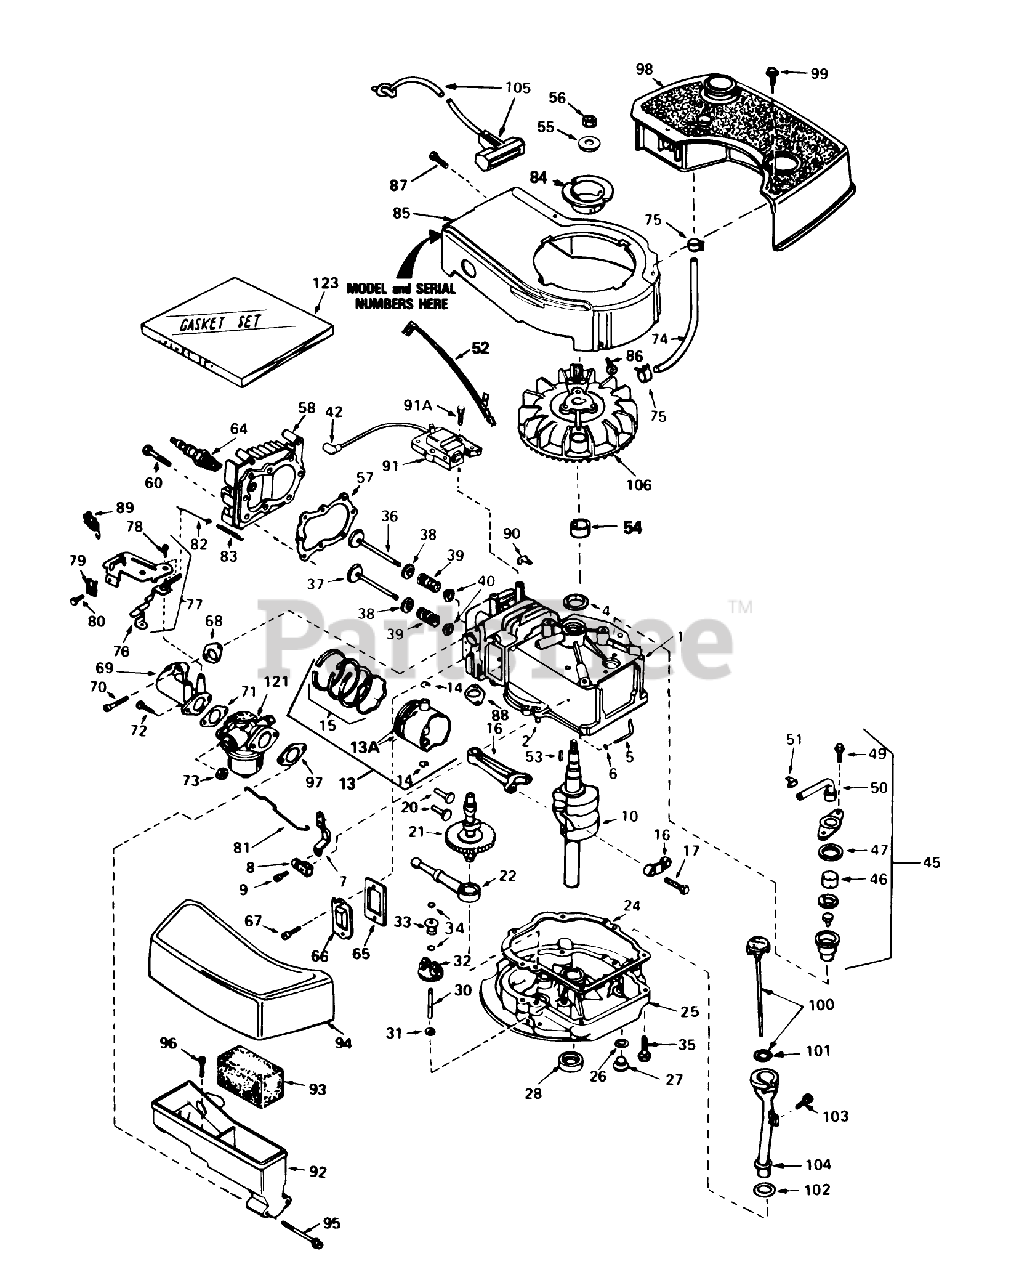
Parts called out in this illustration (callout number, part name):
1	Cyiinder Assy. (Incl. Ref. #2, 4 105)
2	Pin-Dowel
4	Seal-Oil
5	Rod, Governor (Incl. No. 36)
6	Washer-Flat
7	Governor Lever
8	Clamp-Lever, Governor
9	Screw
10	Crankshaft
13	Piston, Pin Ring Assy. (Std.) (Incl. Ref. #13A, 14 15)
13	Piston, Pin Ring Assy. (.010 oversize) (Incl. Ref. #13A, 14 15)
13	Piston, Pin Ring Assy. (.020 oversize) (Incl. Ref. #13A, 14 15)
13A	Piston Pin Assy. (Incl . Ref. . #14) (Std.)
13A	Piston Pin Assy. (Incl. Ref. #14) (.010 Oversize)
13A	Piston Pin Assy. (.020 oversize) (Incl. Ref. #14)
14	Ring-Retaining, Piston Pin
15	Ring Set (Std.)
15	Ring Set (.020" OS)
15	Ring Set (.010" OS)
16	Rod Assy., Connecting (Incl. Ref. #17)
17	OA Bolt-Connecting Rod
20	Lifter-Valve
21	Camshaft(Mech.Comp. Release)
22	Oil Pump ASM
24	Gasket, Mounting
25	Flange Assy., Mounting (Incl. Ref. #26thru 30)
26	Gasket-Oil Drain
27	Plug Oil Drain
28	Seal Oil
30	Shaft-Governor
31	Washer-Flat
32	Governor Gear ASM
33	Spool-Governor
34	Ring-Retaining
35	Screw (1/4-20 x 1-1/4)
36	Valve, Intake (Std.) (Incl. Ref. #40)
36	Valve, Intake (1/32" oversize)(Incl. No. 40)
37	Valve, Exhaust (Std.)(Incl. No. 40)
37	Valve, Intake (1/32" oversize)(Incl. No. 40)
38	Cap-Upper Valve Spring
39	Spring-Valve
40	Cap-Valve, Spring
42	Cover-Spark Plug
45	Breather Assy. (Incl. Ref. #46 thru 51)
46	Element-Breather
47	Gasket-Breather
49	Screw (10-24 x 9/16)
50	Tube, Breaker
51	Clip, Breather
52	Wire-Ground
53	Key-Flywheel
54	Spacer
55	Washer-Belleville
56	Nut-Flywheel
57	63573 GIL 42 SNWTHW
58	Head-Cylinder
60	Screw (5/16-18x1-1/2)
64	Plug, Spark (J17LM or equiv.)
64	Plug, Spark (Champion RCJ-8)
65	Gasket-Breather
66	Cover-Valve
67	Screw
68	Gasket-Intake
69	Pipe, Intake (Incl. No. 68)
70	Screw (1/4-20 x 1)
71	Gasket-Carburetor
73	Nut and Lock Washer (1/4-28)
74	Line-Fuel
75	Clamp-Line, Fuel
76	Lever Control
77	Control Assy., Speed (Incl. Nos, 76, 78 89)
78	Screw, Hex Washer Hd Shoulder Self-Tap
79	Conduit
80	Screw (10-32 x 3/8)
81	Link-Throttle
82	Link Governor Spring
83	Spring Governor
84	Hub-Starter
85	Housing Blower
86	Screw (1/4-20x19/32)
87	Screw (10-24 x 9/16)
88	Gasket Exhaust
89	Terminal
90	Clip-Wire
91	Solid State
91A	Screw
92	Body Air Cleaner
93	Filer, Air
94	Cove, Air Cleaner
95	Screw Fil Hd.
96	Screw, Hex Hd.
97	Gasket-Air Cleaner
98	Tank-Fuel
99	Screw (10-32 x 35/64)
100	Dipstick, Oil (Incl. Ref. #101)(Twist Lock)
101	O-Ring
102	Gasket
103	Screw (10-32 x 1/2)
104	Tube-Oil Fill
105	Rope Assy., Starter
106	Flywheel
121	Carburetor (Incl. Ref. #71)
123	Gasket Set
